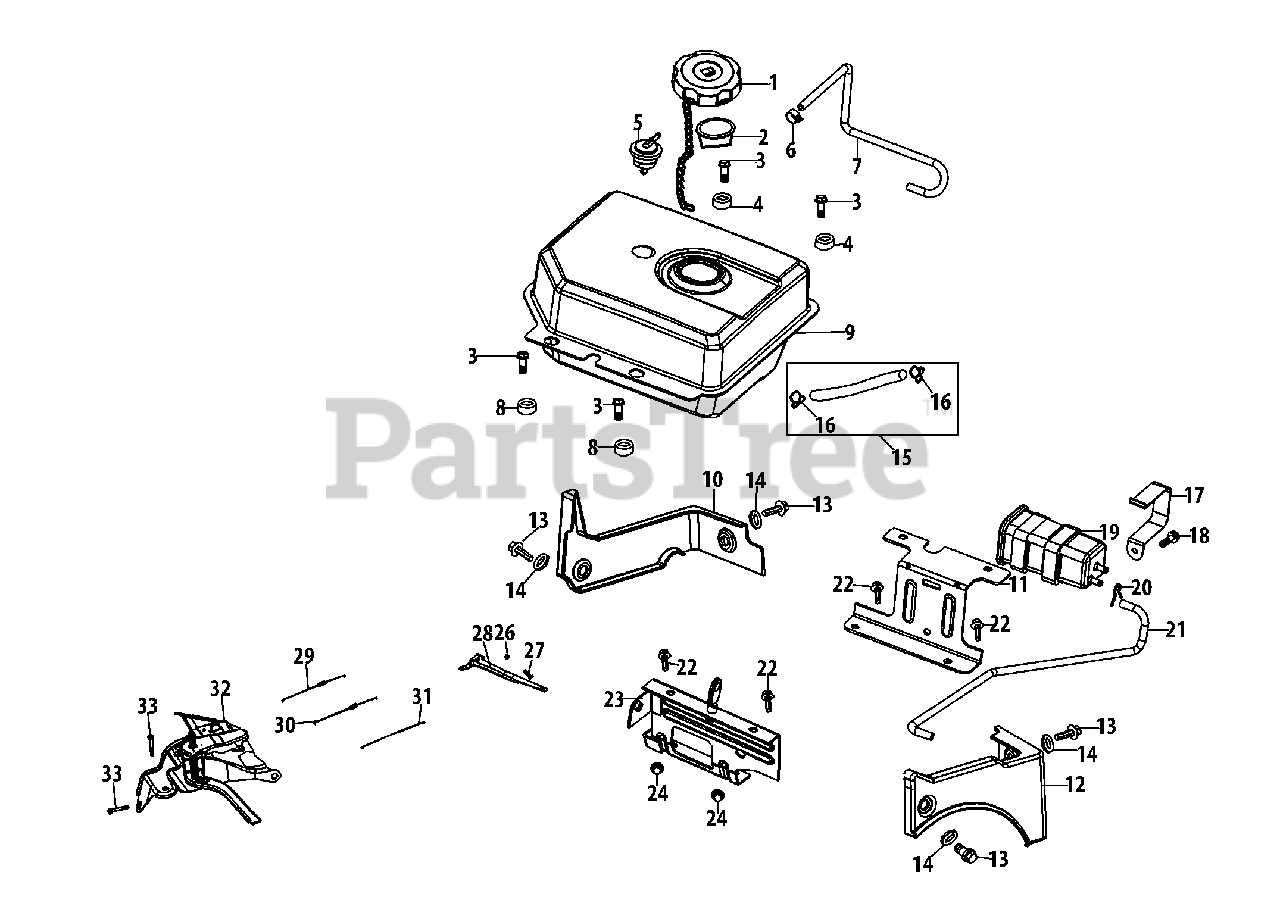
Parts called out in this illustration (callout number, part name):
1	Fuel Cap Assembly
2	Fuel Level Indicator
3	Bolt M8×20
4	Gas Tank Isolator
5	Rollover Valve Assembly
6	Fuel Hose Clamp
7	Primer Hose
8	Gas Tank Isolator
9	Fuel Tank Assembly
10	Governor Cover
11	Rear Mounting Bracket Assy.
12	Decorate Cover
13	Bolt M6×16
14	Isolator Bushing
15	Fuel Line Kit
16	Fuel Hose Clamp
17	Carbon Canister Bracket
18	Bolt M6×12
19	Carbon Canister
20	Breather Hose Clamp
21	Primer Hose
22	Bolt M8×14
23	Gas Tank Support Bracket
26	Nut M6
27	Governor Arm Bolt
28	Governor Arm
29	Governor Spring
30	Throttle Linkage Spring
31	Throttle Linkage
32	Component Bracket
33	Bolt, M6×14
